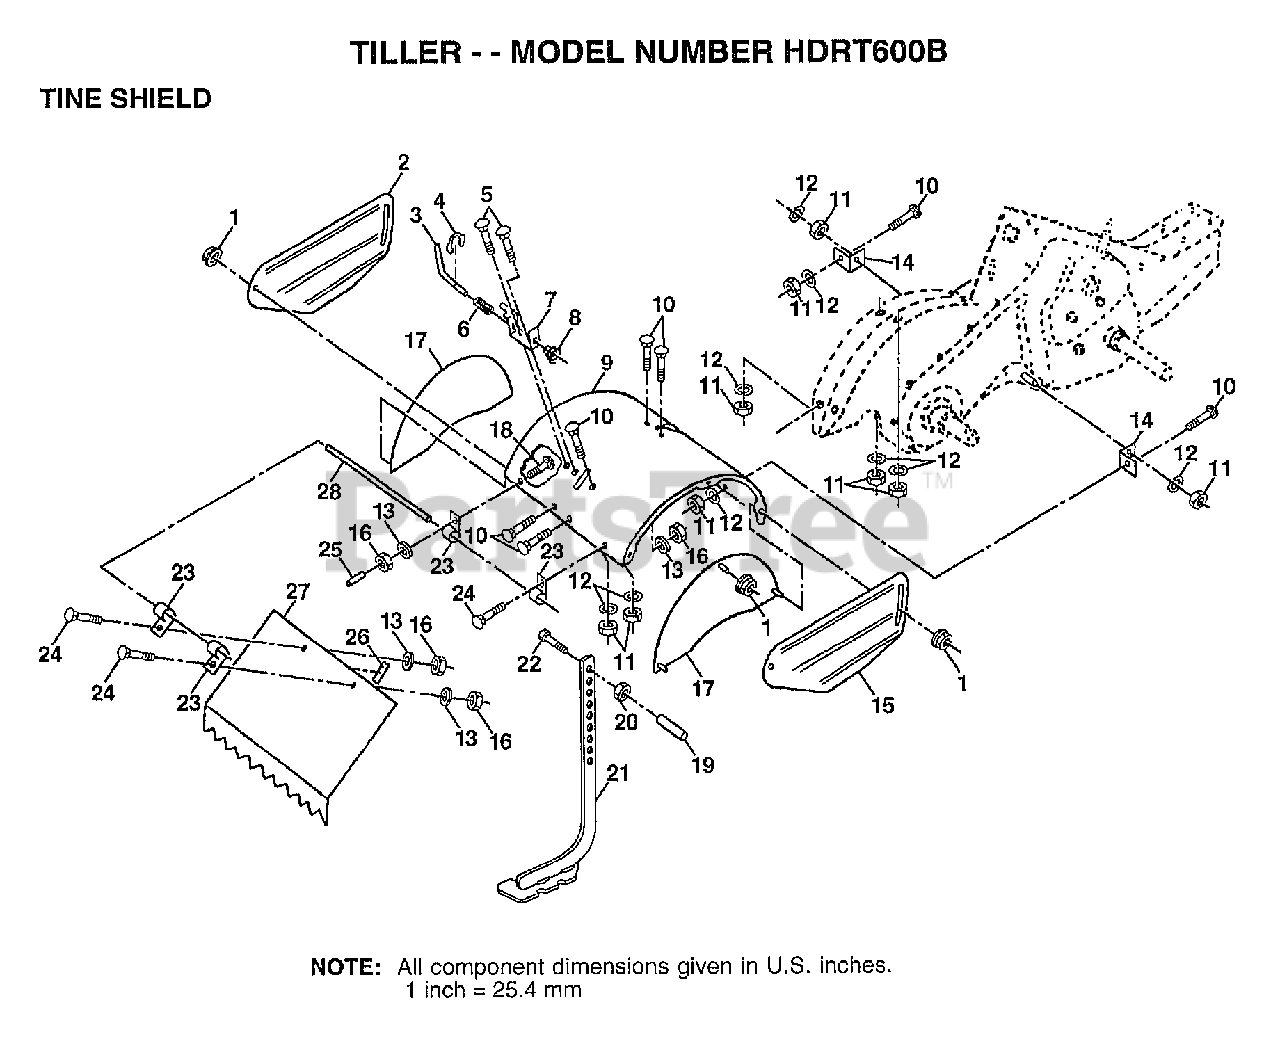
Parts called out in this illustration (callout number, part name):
1	NUT
3	STAKE PIN TI
4	KLIP RING TI
5	BOLT
6	SPRING TI
7	LATCH BRACKET TI
8	SPRING CRT
10	BOLT
11	NUT.HEX.5/16-18
12	LOCKWASHER
13	LOCKWASHER
14	TINE SHLD BRKT TI
18	BOLT
19	GRIP CRT
20	NUT.HEX.3/8-16UNC
21	STAKE.ASM.DEPTH
22	BOLT
23	HINGE CRT
24	BOLT.1/4-20X1/2
25	VINYL CAP TI
26	PAD IDLER TI
27	SHIELD.LEVELING
28	PIN.HINGE
